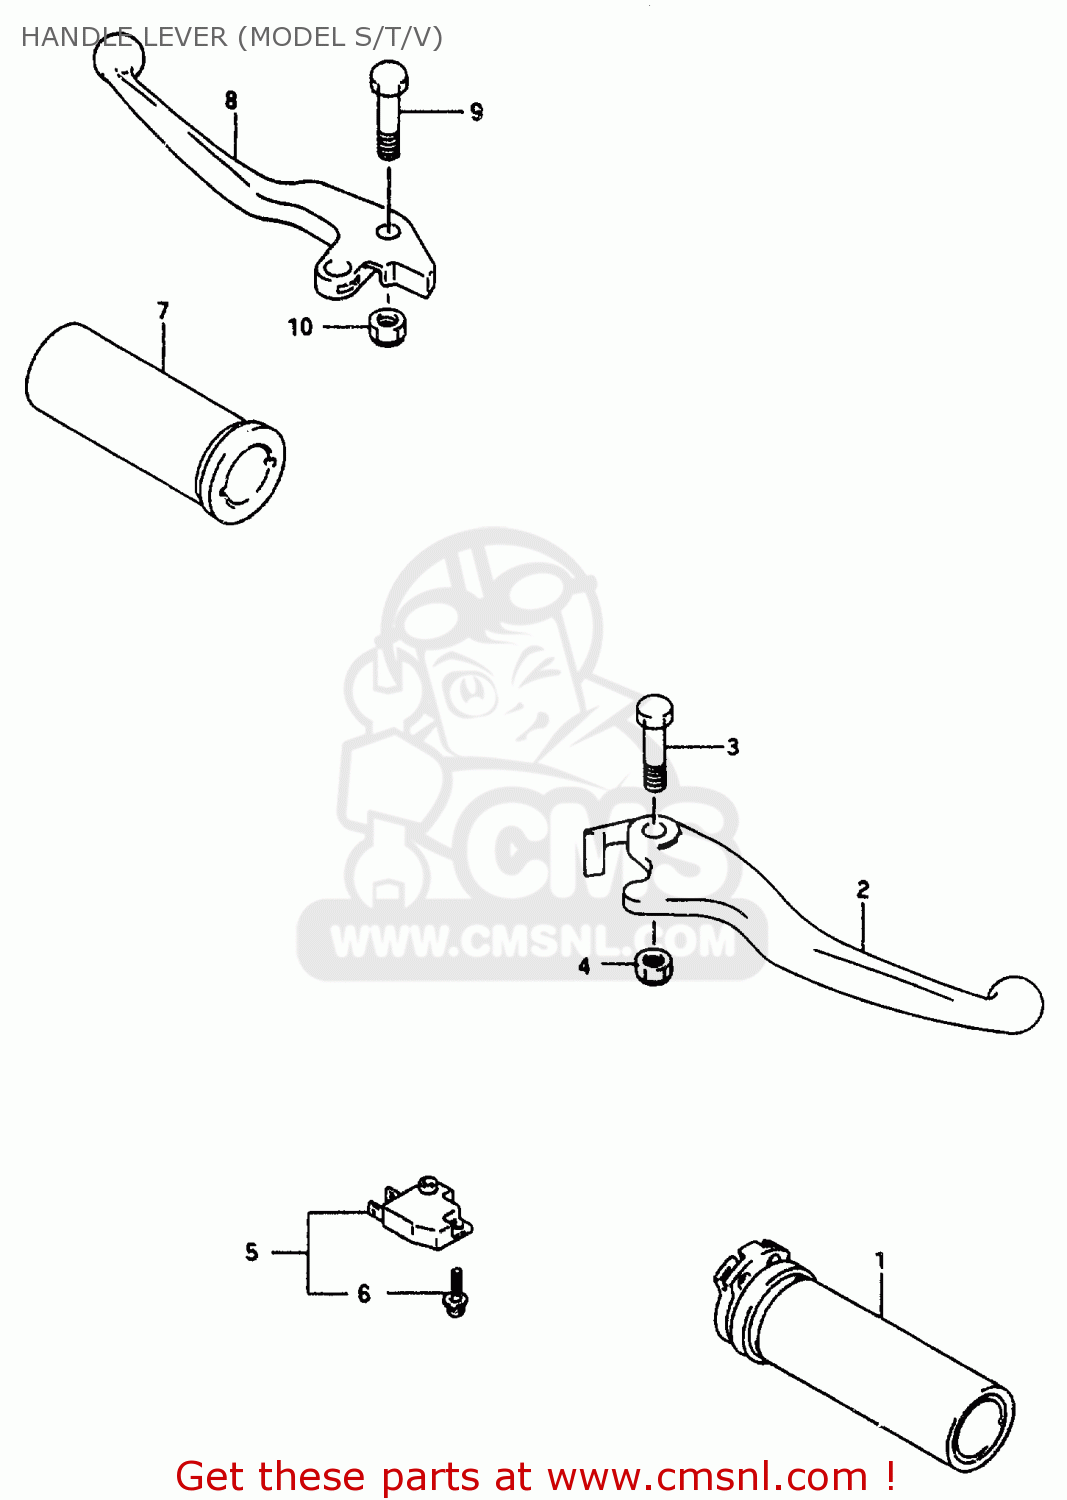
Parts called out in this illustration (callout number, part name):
1	GRIP,THROTTLE
2	LEVER,BRAKE
3	BOLT,LEVER SET
4	NUT 6MM
5	SWITCH ASSEMBLY,STOP
6	SCREW
7	GRIP,L
8	LEVER,CLUTCH (SILVER)
9	BOLT,LEVER SET
10	NUT 6MM
